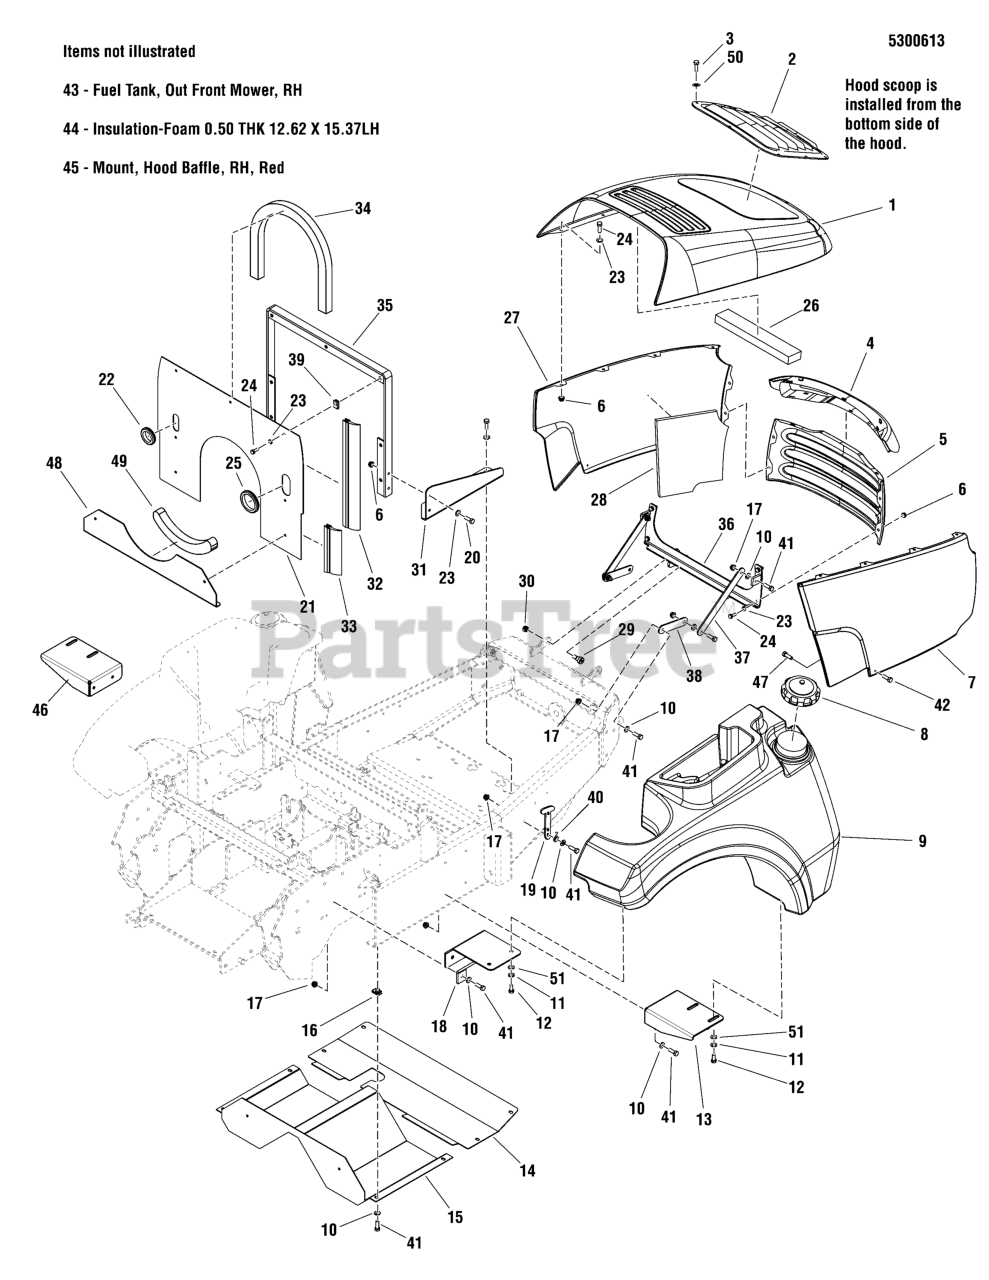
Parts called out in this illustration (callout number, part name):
1	HOOD, BOXED, S800X - SPR RED
2	SCOOP, HOOD, OUTFRONT MOWER
3	RIVET-POP.188 .429L AL,AL STEM.37HD DIA
3	POP RIVET, 3/16" X .575"(.251-.375GP)BLK
4	MACHINED BLACK LENS, OUT FRONT MOWER
5	GRILLE, PERF METAL, OUT FRONT MOWER - RED
6	NUT, 1/4-20 Hex Nylock Flange
7	PANEL-SIDE, 18GA LEGACY - PLAIN
8	FUEL CAP, 3-1/2", MANAGED VENT OUT, 12"
9	FUEL TANK, OUT FRONT MOWER, LH
10	WASHER, 5/16" SAE
11	WASHER, 5/16 LOCK CZ
12	BOLT, 5/16-18 X 3/4 GD5
13	WELD, TANK MOUNT, LH - RED
14	DEBRIS GUARD, ENGINE - RED
14	PLATE, GUARD, PERFORATED - RED
15	DEBRIS GUARD, PUMP - RED
16	BODY CLIP, 5/16-18-7GA MATERIAL
17	NUT, 5/16-18 HEX NYLOCK FLANGE NUT
18	MOUNT, FUEL TANK WELDMENT - FRONT - RED
19	STRAP,HOOD,BLACK RUBBERCLAMP, HOSE, 1.000 DIA.
20	BOLT, 1/4-20 X 1" GD5 CZ
21	PLATE, HOOD BAFFLE, LOWER - RED
22	GROMMET, 1-1/4"
23	WASHER, 1/4 SAE
24	SCREW-HEX WZ LOCK FLNG 1/4-20X0.625 BLK
25	GROMMET, 2" ID
26	FOAM HOOD SEAL, OUT FRONT MOWER
27	PANEL-SIDE, 18GA LEGACY - PLAIN
28	INSULATION-FOAM 0.50 THK 12.62 X 15.37RH
29	BOLT, 3/8-16 X 3/8", 1/2" SHOULDER
30	NUT, Hex, Side Lock, 3/8-16
31	MOUNT, HOOD BAFFLE, LH - RED
32	SEAL, WIPER, CLIP ON, 14.75
33	SEAL, WIPER, CLIP ON, 6
34	SEAL, FLYWHEEL SCREEN, FOAM
35	WELD., HOOD BAFFLE FRAME - RED
36	WELD, HOOD MOUNT - RED
37	LINK, HINGE, LONG - RED
38	LINK, HINGE, SHORT - RED
39	BODY CLIP, 1/4-20 X 1/2" DEEP
40	HOOK-.125DIA WIRE GR CAT STRAP YELLOW
41	BOLT, 5/16-18 X 1" GRD5 YZ
42	BINDING POST #8-32X.500 INT THR BLK
46	WELD, TANK MOUNT, LH - RED
47	SCREW-HEX SERR FLNG LK # 8-32X0.375 YEL
48	PLATE HOOD BAFFLE, BOTTOM - RED
49	FOAM, ENGINE FAN SEAL, OUTFRONT, BOTTOM
50	WASHER, #10 SAE
51	WASHER, 5/16 GRADE 9, FLAT
